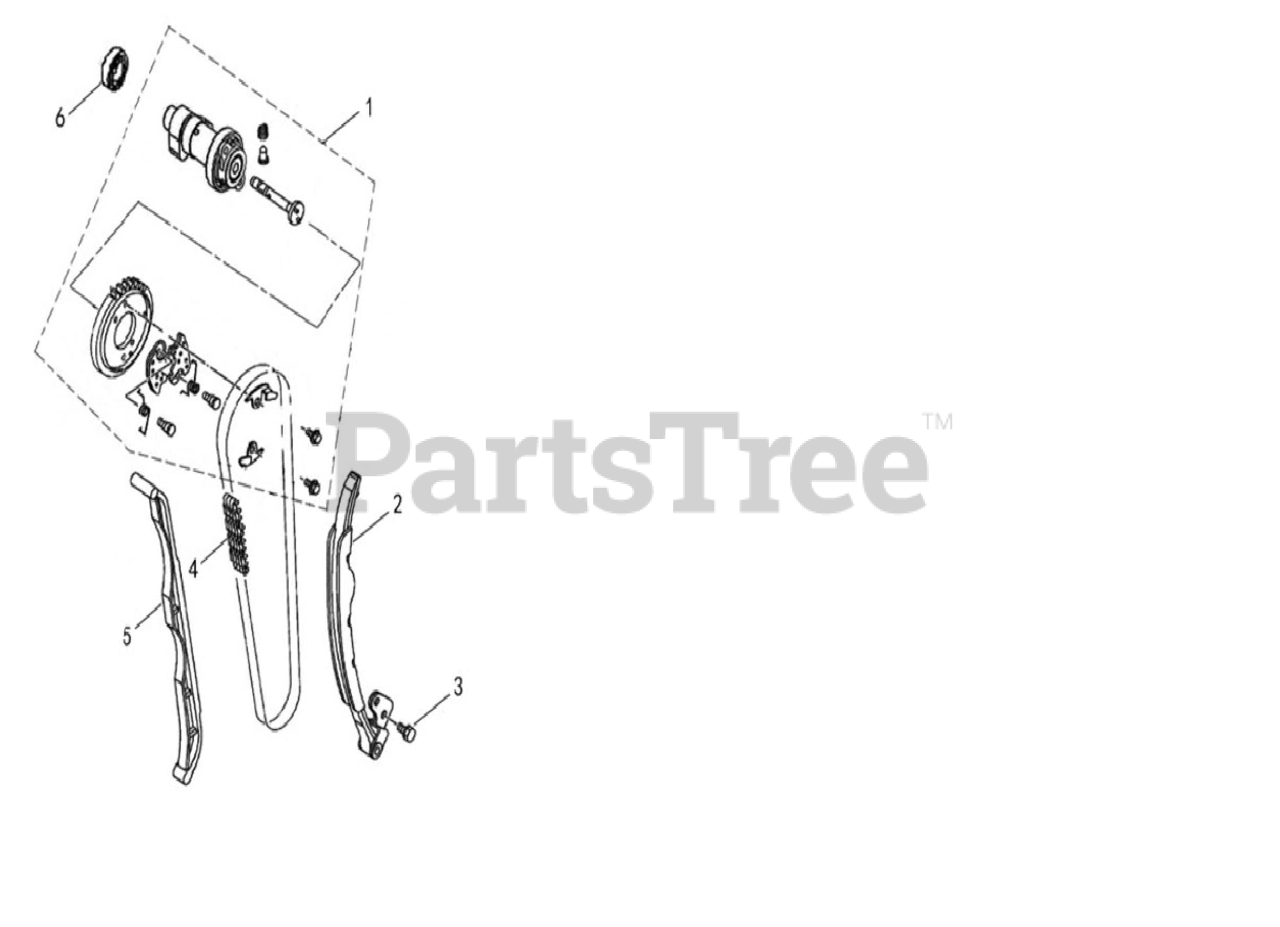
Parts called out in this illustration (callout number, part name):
1	CAMSHAFT ASSEMBLY
2	Tensioner Plate
3	Hex head bolt & plain washer M6X16
4	TIMING CHAIN M7-6.35-124
5	CHAIN GUIDE
6	BEARING 6004Z
